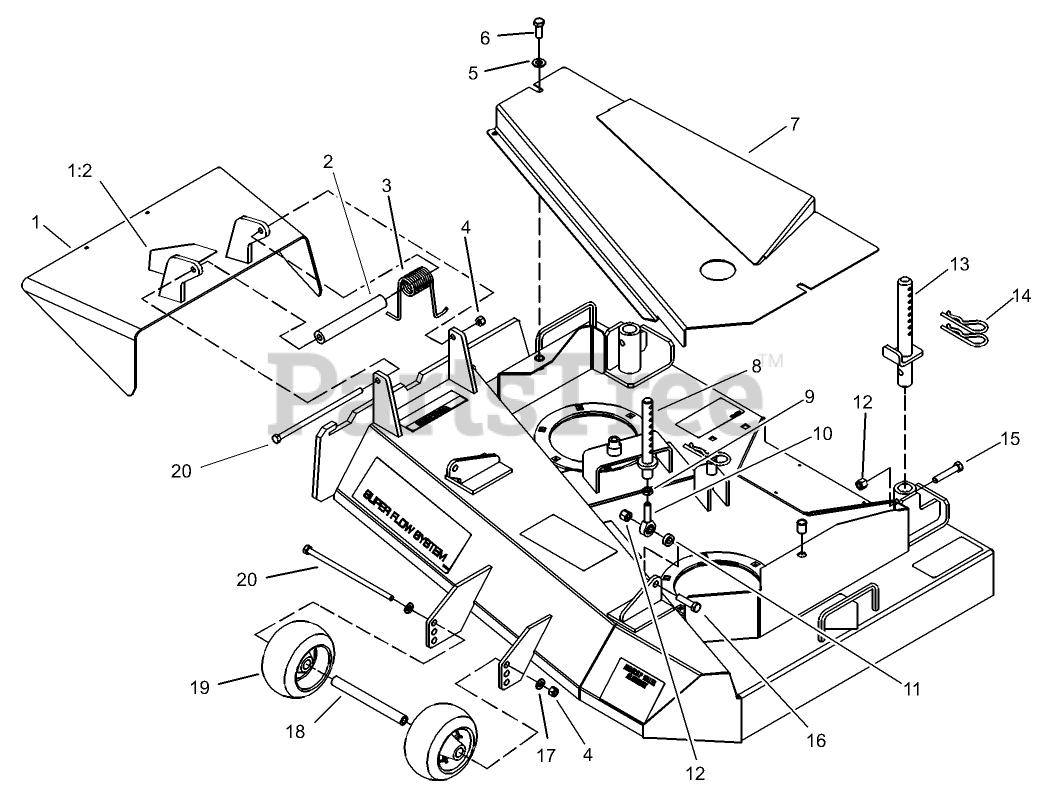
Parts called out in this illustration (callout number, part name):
1	DEFLECTOR ASM
1:2	DECAL-DANGER
2	SPACER
3	SPRING-TORSION
4	NUT-LOCK, NI
5	WASHER-FLAT
6	SCREW-HH
7	COVER ASM
8	FRONT PIN ASM
9	NUT-HJ
10	BALLJOINT
11	SPACER
12	NUT-LOCK, NI
13	REAR PIN ASM
14	PIN-HAIR
15	SCREW-HH
16	SCREW-HH
17	WASHER-PLAIN
18	SPACER-WHEEL
19	WHEEL-GAGE
20	SCREW-HH
